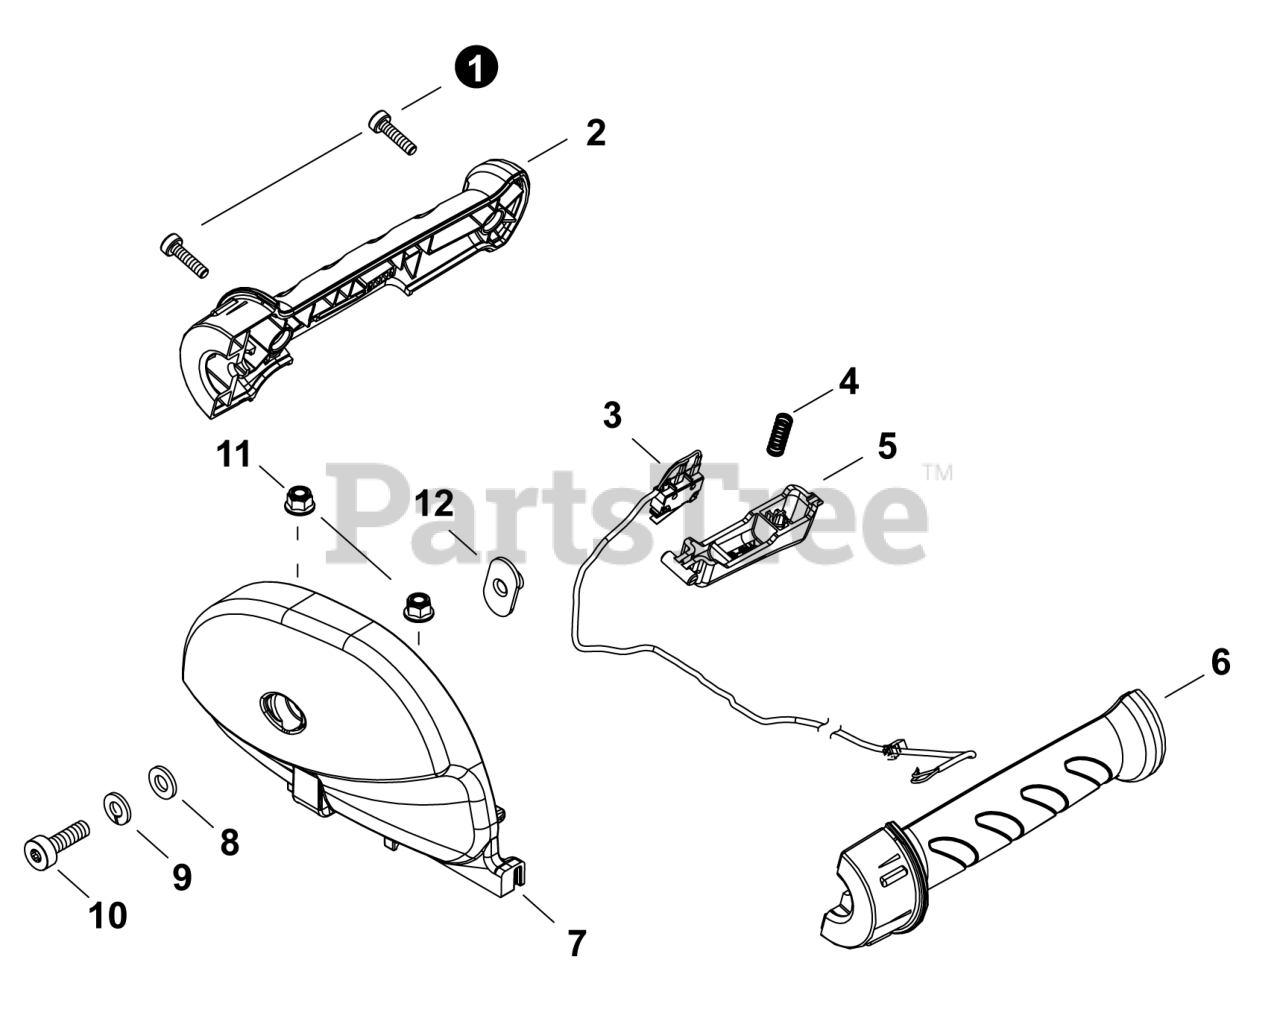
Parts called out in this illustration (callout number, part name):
1	BOLT, TORX 4x16
2	GRIP, HANDLE - RIGHT
3	HARNESS, WIRE - HANDLE
4	SPRING, COMPRESSION
5	LEVER, SAFETY
6	GRIP, HANDLE - LEFT
7	GUARD, HAND
8	WASHER 6
9	WASHER, SPRING 6
10	BOLT, TORX 6x20
11	NUT, FLANGE M5
